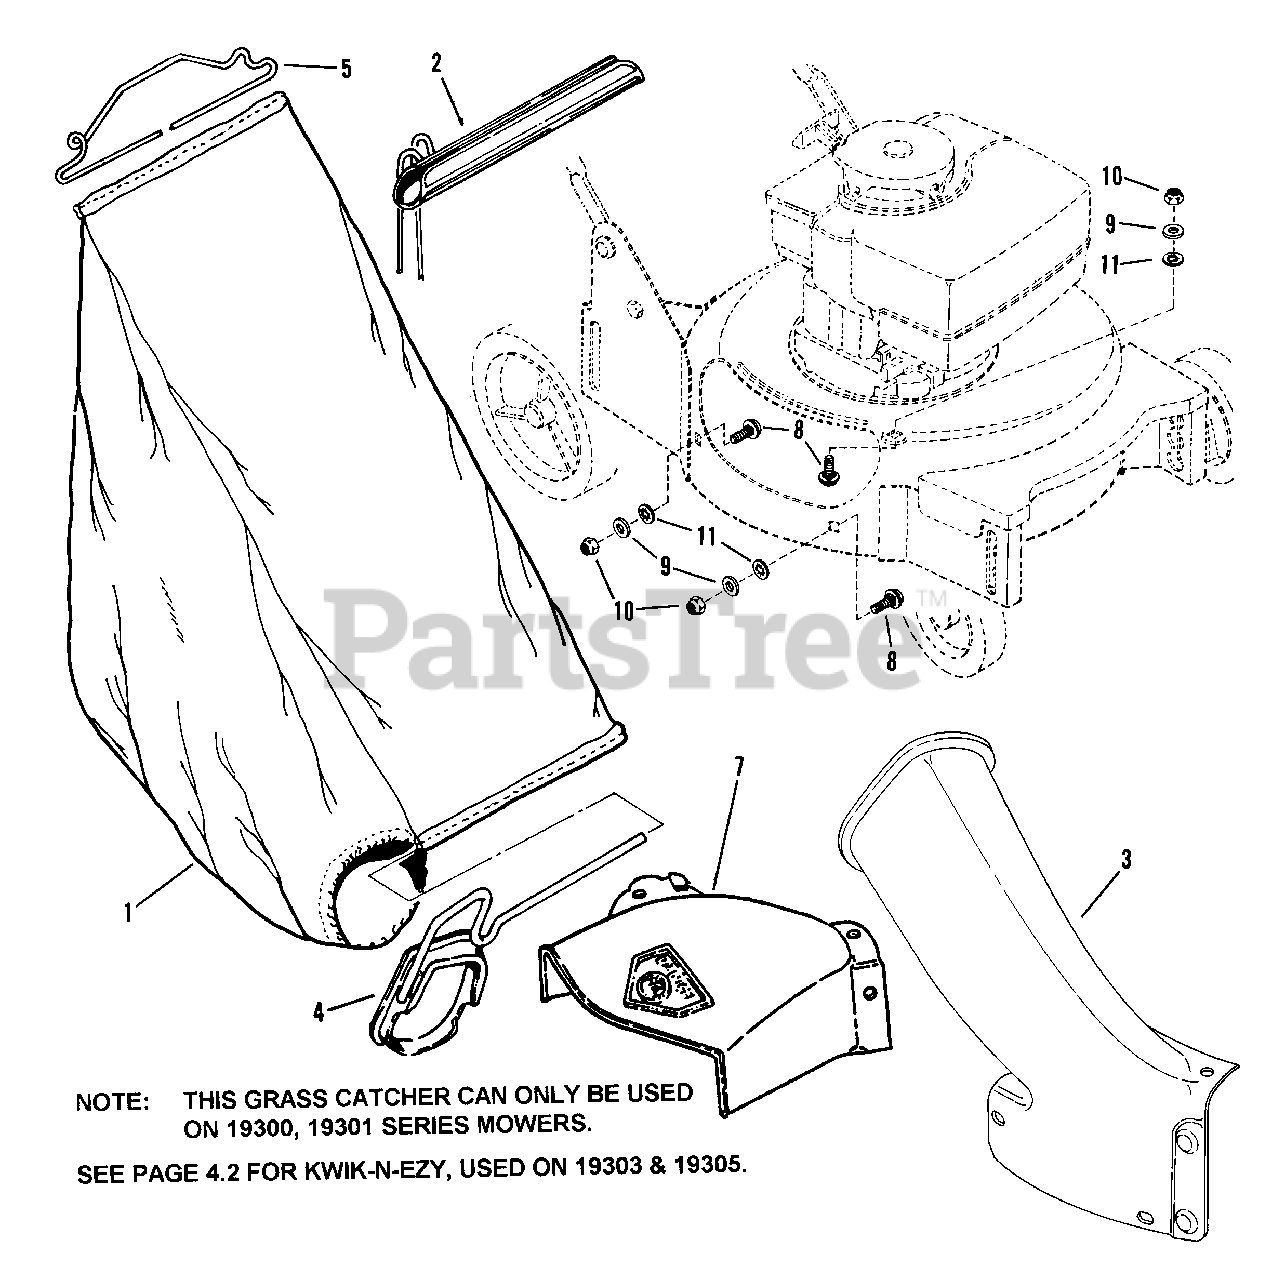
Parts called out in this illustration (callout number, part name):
1	BAG, Grass
2	ASSEMBLY, Rope & Slider
3	ADAPTER, Bag
4	CONNECTOR, Bag
5	WIRE, Rear Bag
6	WING-NUT, 5/16-18
7	CHUTE, Side 20"
8	BOLT, 5/16-18 x 5/8" Short Neck Carriage, Grade 5
9	WASHER, 5/16 Flat
10	NUT, 5/16-18 Nyloc
11	RETAINER, 5/16 Bolt
